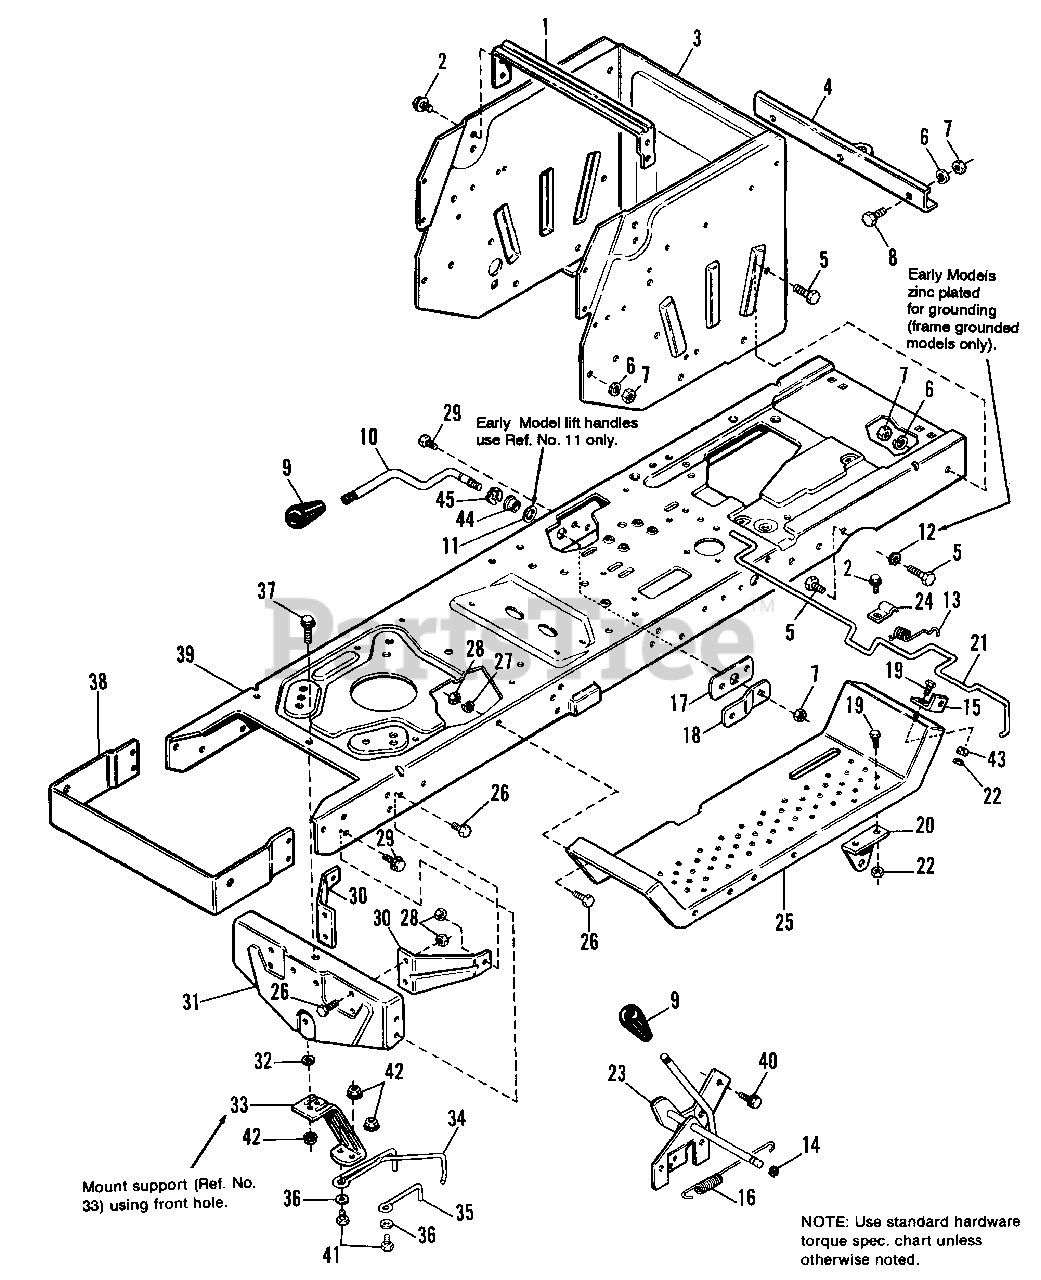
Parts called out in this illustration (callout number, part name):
1	BRACE, Seat
2	SCREW, Taptite, 5/16-18 x 1/2
3	SUPPORT, Axle Wrapper
4	BAR, Draw
5	CAPSCREW, Hex, 3/8-16 x 1
6	LOCKWASHER, 3/8
7	NUT, Hex, 3/8-16
8	CAPSCREW, Hex, 3/8-16 x 3/4
9	KNOB, Handle
10	HANDLE, Lift
12	LOCKWASHER, Ext. Tooth, 3/8, Zinc Pltd.
13	SPRING, Torsion
14	RING, Retaining
15	BRACKET, Seat Latch
16	SPRING, Extension
17	BAR, Support
18	ARM, Support
19	CAPSCREW, Hex, 1/4-20 x 5/8
20	SUPPORT, Clutch
21	ROD, Latch
22	NUT, Hex, 1/4-20
23	HANDLE ASSY., PTO Clutch
26	CAPSCREW, Hex, 5/16-18 x 3/4
27	LOCKWASHER, 5/16
28	NUT, Hex, Full, 5/16-18 (Qty. 18 on 8 HP)
29	SCREW, Taptite, 5/16-18 x 3/4
30	BRACE, Axle Support
31	SUPPORT, Axle
32	WASHER, Plain, 11/32-1 x 10 Ga.
36	WASHER, 11/32
37	CAPSCREW, Hex Hd., Flange, 5/16-18 x 1-1/4
40	SCREW, Taptite, 1/2
41	CAPSCREW, Hex, 5/16-18 x 7/8
42	LOCKNUT, Hex, Flange Whiz, 5/16-18
43	WASHER
45	KLIPRING, 1/2
